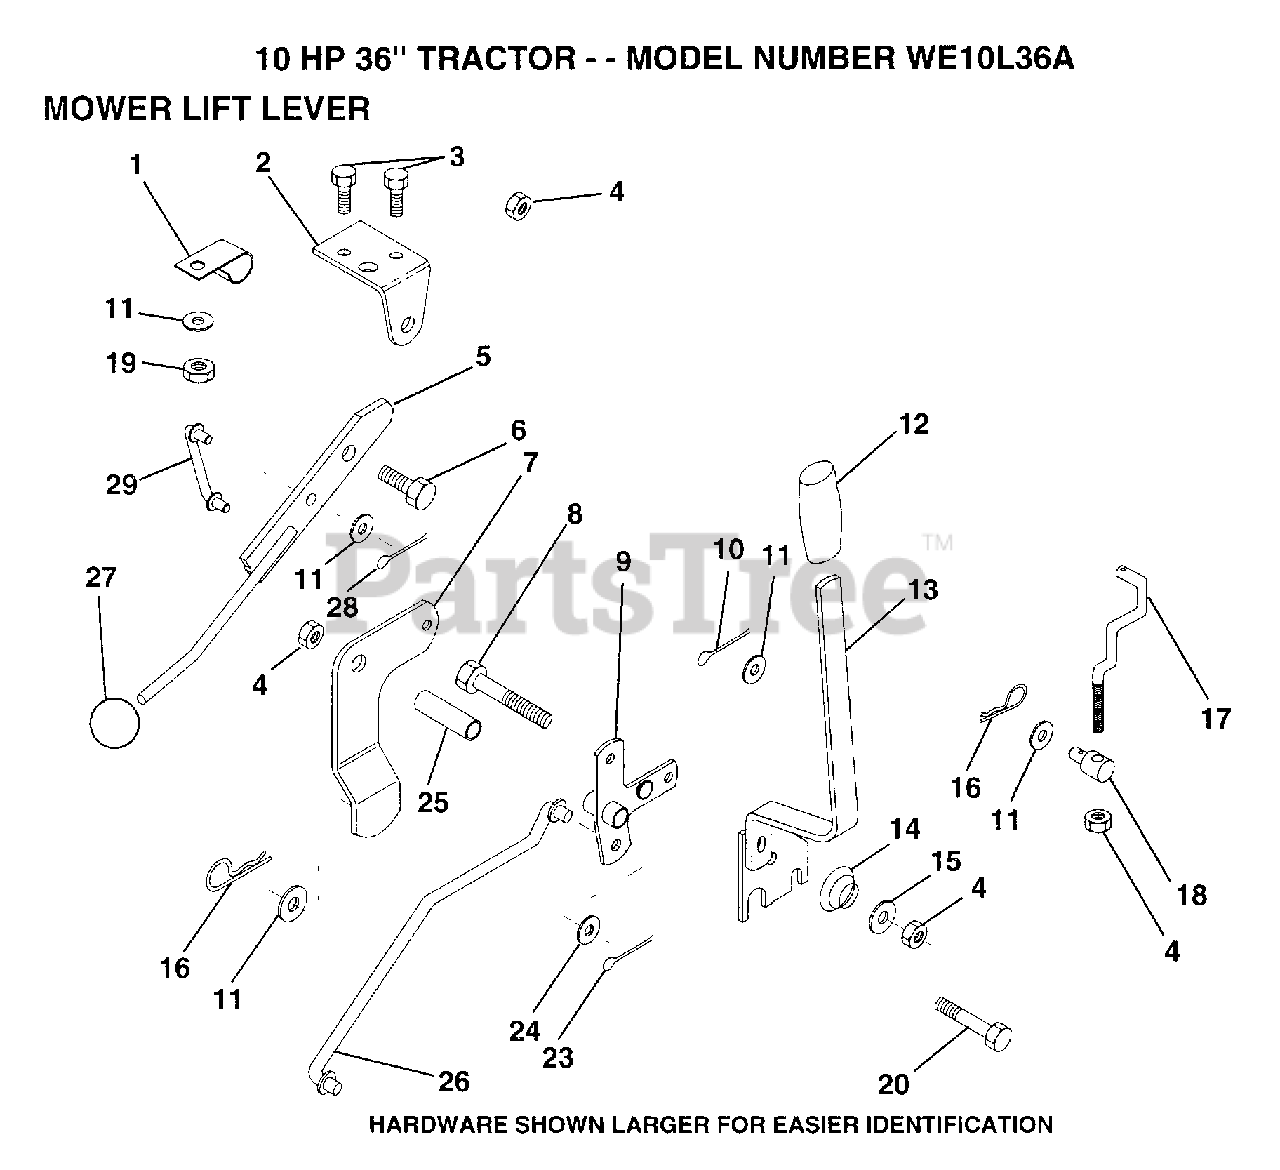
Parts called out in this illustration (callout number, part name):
1	"CLIP,INSULATOR"
2	BRKT CLUTCH
3	BOLT
5	CLUTCH LEVER AS
6	"BOLT, SHOULDER LT"
7	MWR CLUTCH ARM AS
8	BOLT
9	"BELLCRANK,LIFT"
10	COTTER PIN
11	WASHER
13	HANDLE.ASM.LIFT
14	SPRING COMPRESSIO
15	WASHER T
16	SPRING.RETAINER
17	"LINK,LIFT FRT"
18	TRUNION
20	BOLT
23	PIN COTTER 1/8
25	TUBE SPACER
26	"ROD,MOWER LIFT "
27	KNOB T(3/8 HOLE)
29	CLUTCH LINK
